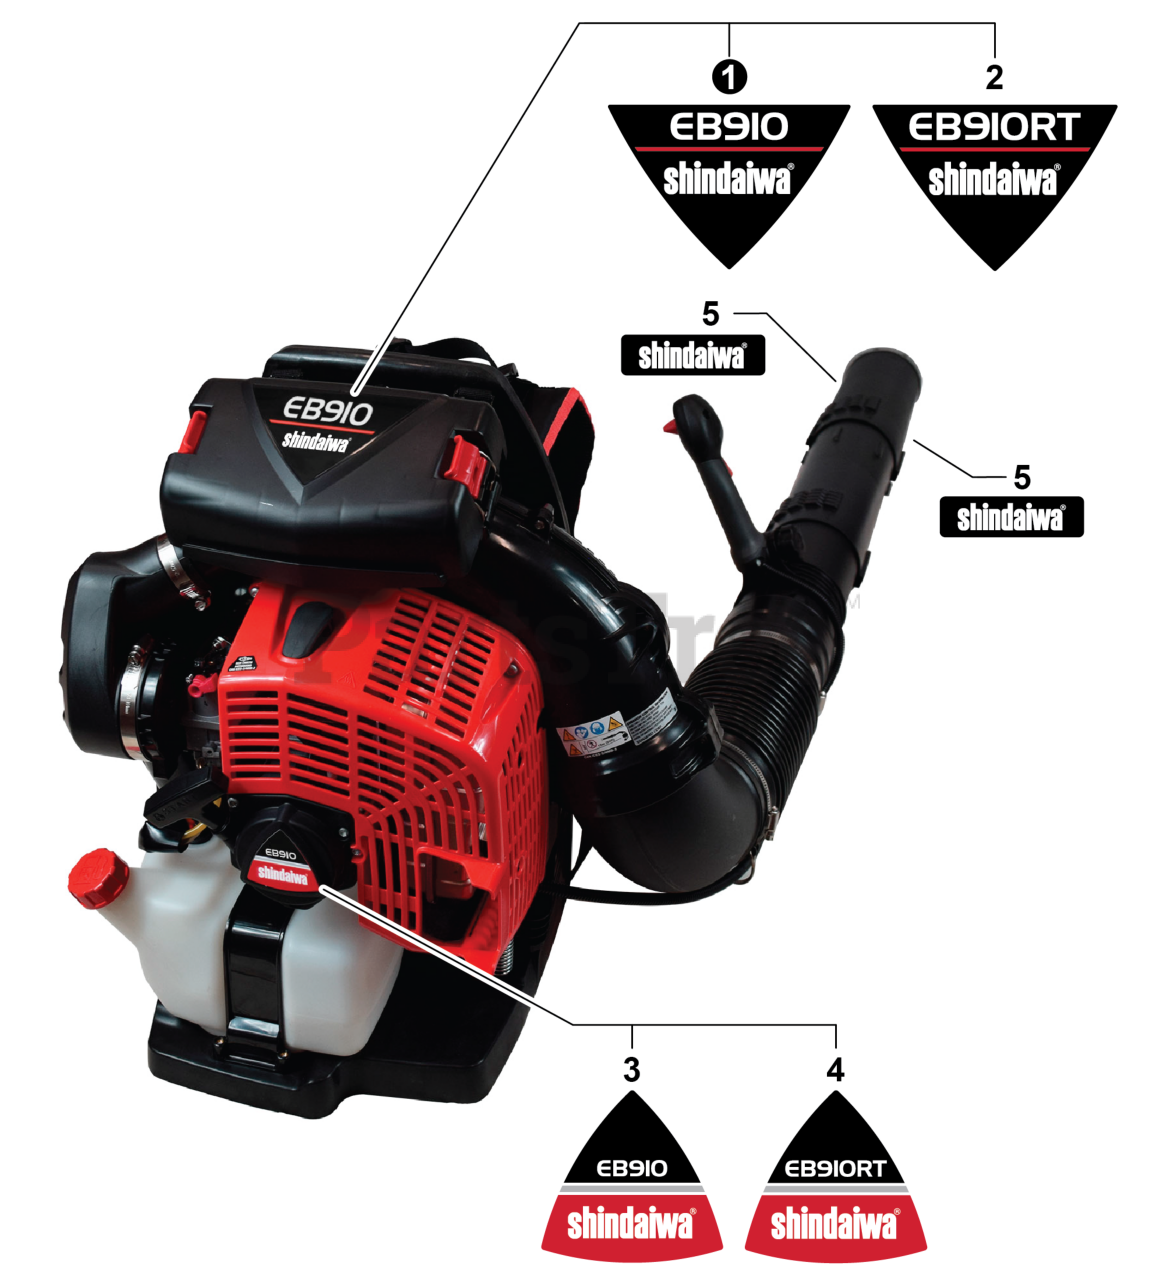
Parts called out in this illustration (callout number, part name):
1	LABEL - EB910
2	LABEL - EB910RT
3	LABEL - EB910
3	LABEL - RECOIL STARTER - EB910
4	LABEL - RECOIL STARTER - EB910RT
4	LABEL - EB910RT
5	LABEL - SHINDAIWA BLOWER TUBE
